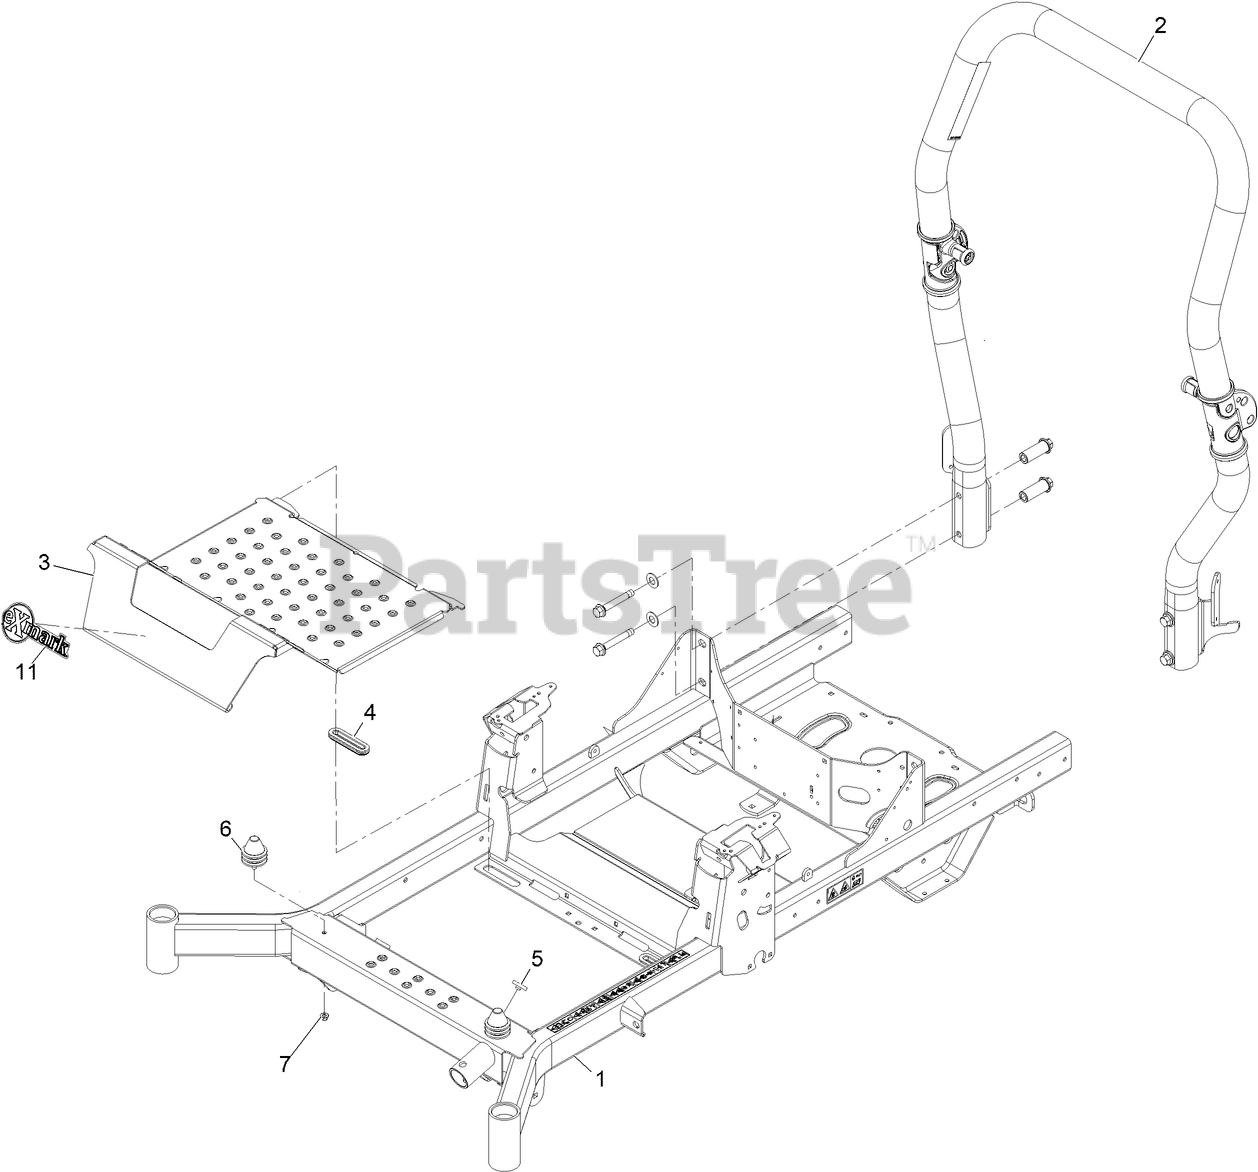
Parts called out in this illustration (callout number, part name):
1	ASM, Frame W/ Decals
2	ASM, ROPS
3	Pan-Floor
4	GROMMET-RUBBER
5	BUMPER-PUSH-IN, RUBBER
6	ISOLATOR
7	NUT-HF, NI
11	DECAL-EXMARK LOGO
